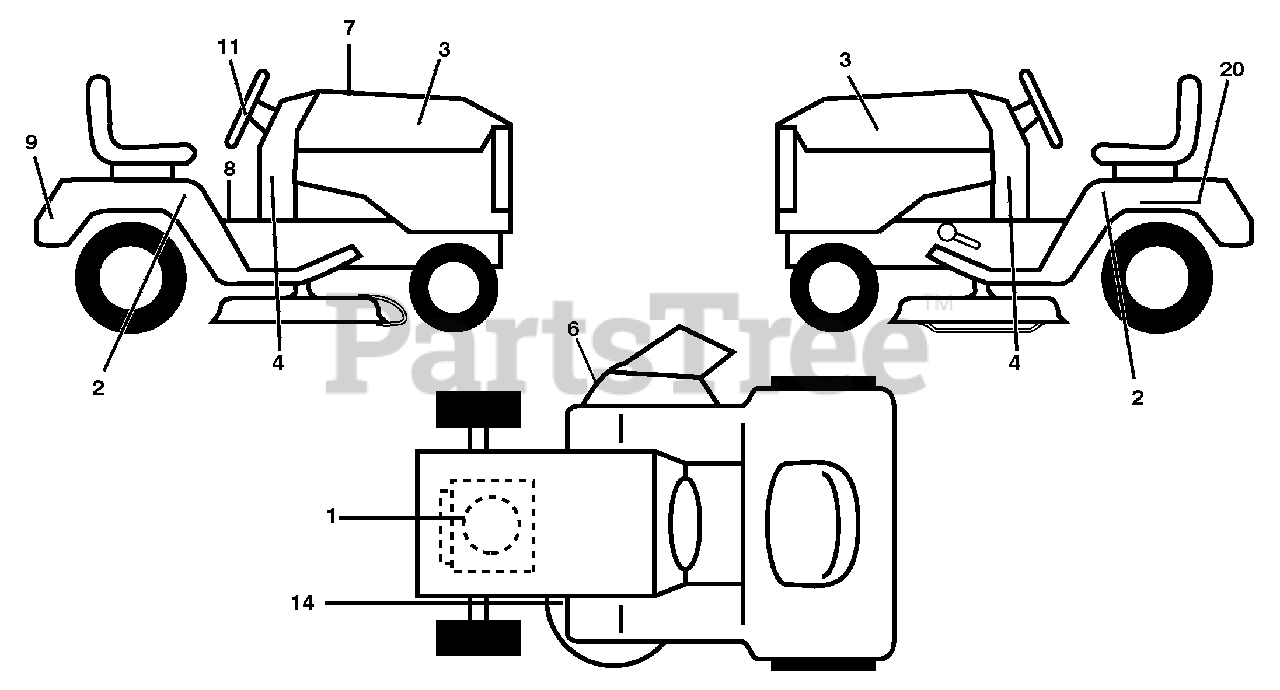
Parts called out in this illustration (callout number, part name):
1	Decal Engine HP
2	Decal Fender RH/LH
3	Decal Hood RH/LH
4	Decal LWD. Dash
6	Decal Warning Dflect/Cut Finger
7	Decal Replacement Parts
8	Decal Fender Warn S/F
9	Decal Fender Logo
11	Decal Ins Strg Whl
14	Decal V-Belt Schematic
20	Decal Bat Dan/Psn
20	Pad Footrest LH
20	Pad Footrest RH
20	Manual Operator's (English/French)
20	Manual Operator's (Spanish)
20	Manual Parts (English)
